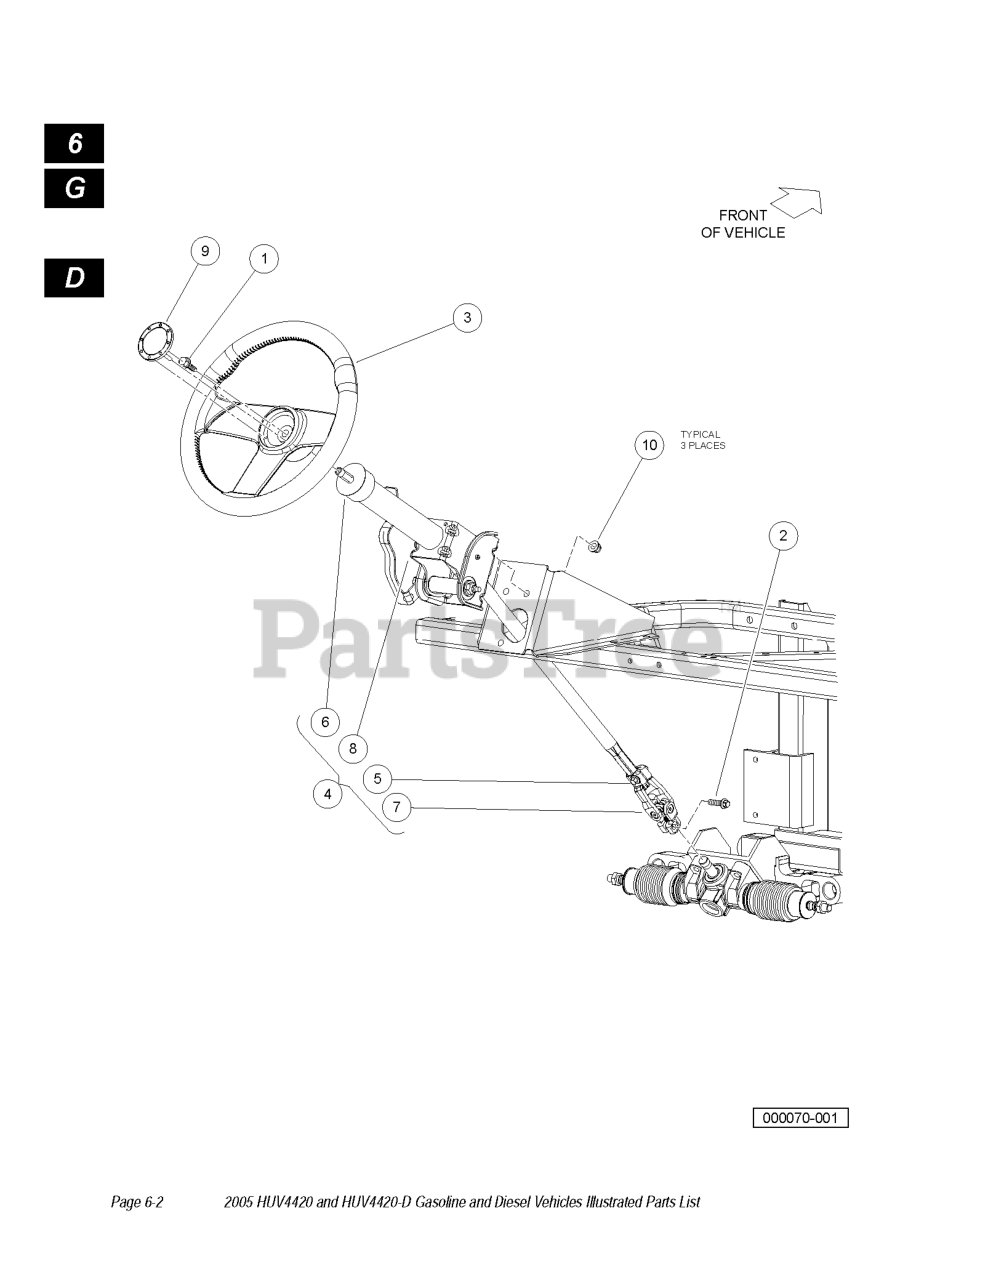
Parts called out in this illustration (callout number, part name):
1	BOLT, M10 X 20 HEX WASHER HD
2	BOLT - FLANGED HD, M8 X 30.0
3	STEERING WHEEL, VIPER, HEX HUB
4	STEERING COLUMN
5	BOLT - FLANGED HD, M8 X 30.0
6	SHROUD, STEERING COLUMN, PREC
9	CAP, STEERING WHEEL, VIPER
10	LOCK NUT, FLG M8 X 1.25 NYLON
